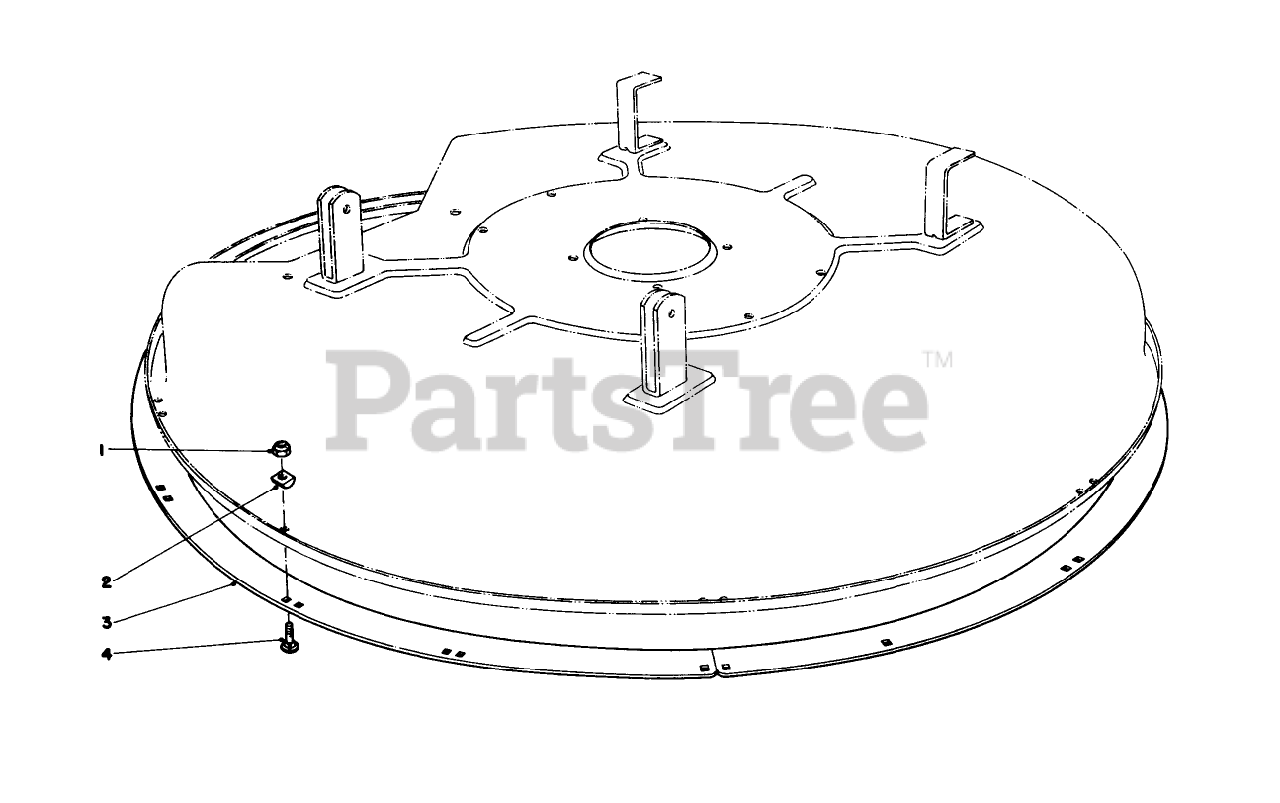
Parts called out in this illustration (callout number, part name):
1	NUT-LOCK, NI
3	DECK RING *B
4	BOLT-CARR
